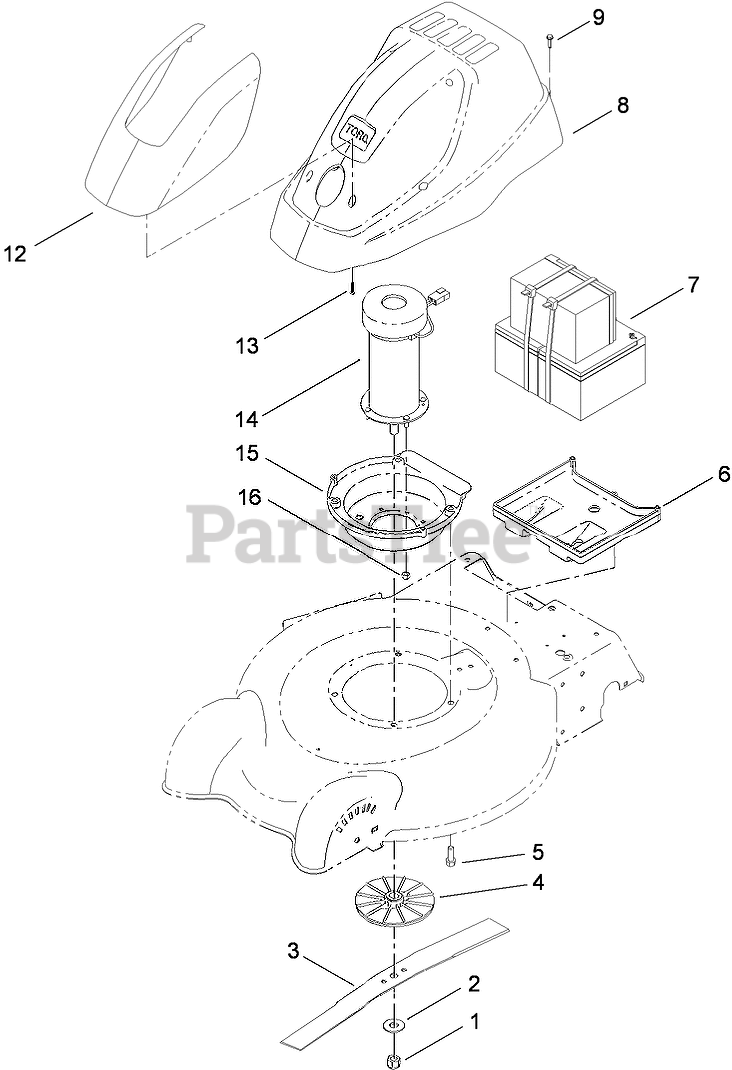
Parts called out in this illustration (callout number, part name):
1	NUT-HEX
2	WASHER-FLAT
3	BLADE-20 INCH
4	FAN MOTOR ASM
5	SCREW-TAPTITE
6	TRAY-BATTERY
7	BATTERY ASM
8	SHROUD ASM
9	SCREW-HWH
12	COVER-SHROUD
13	SCREW-PPH
14	MOTOR-36V
15	BASE-MOTOR
16	NUT-LOCK, NI
